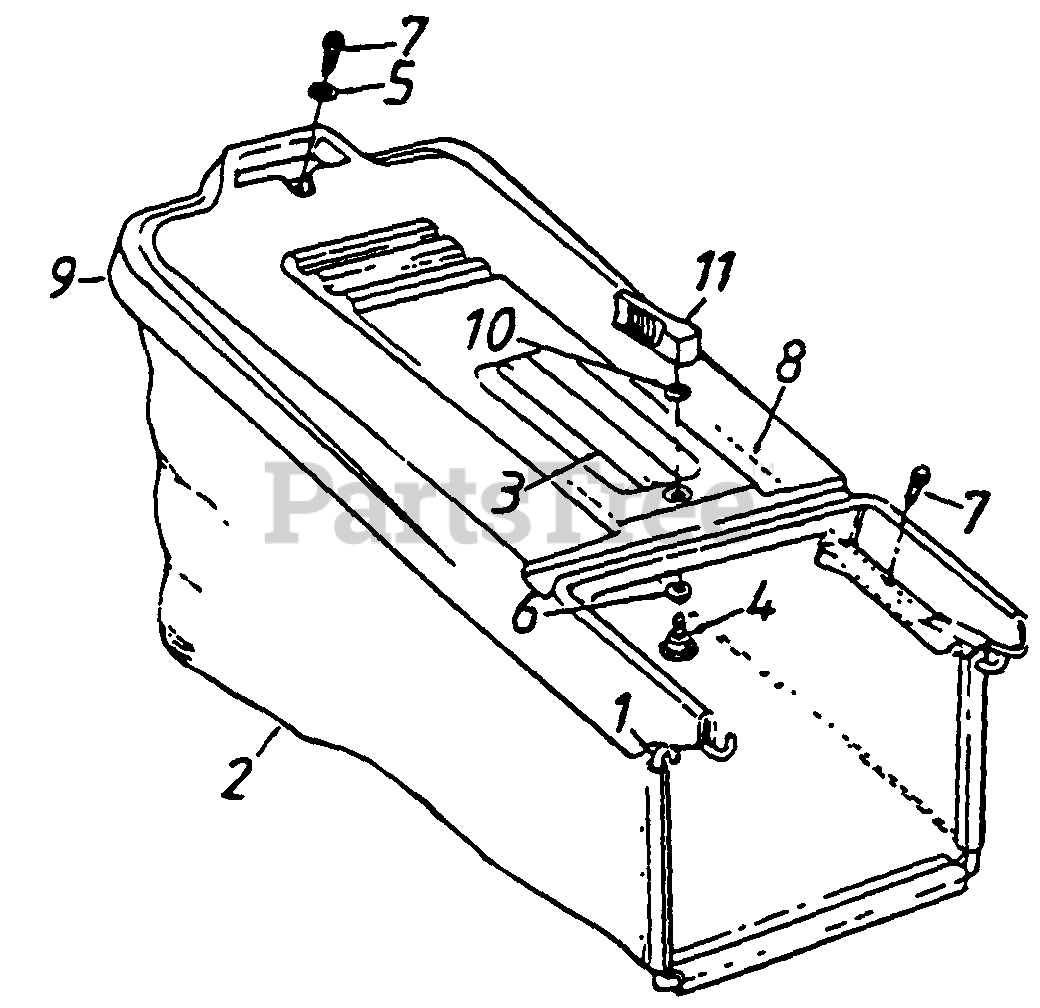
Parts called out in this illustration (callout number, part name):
2	Grass Bag
3	Hardtop Handle
4	Shoulder Bolt
5	Fl-Wash .281" I.D.
6	Bowed Washer
7	Hex L-Wash. AB-Tap Scr. 1/4 x .62"
10	Internal I-Wash. 1/4" I.D.
11	Locking Knob
